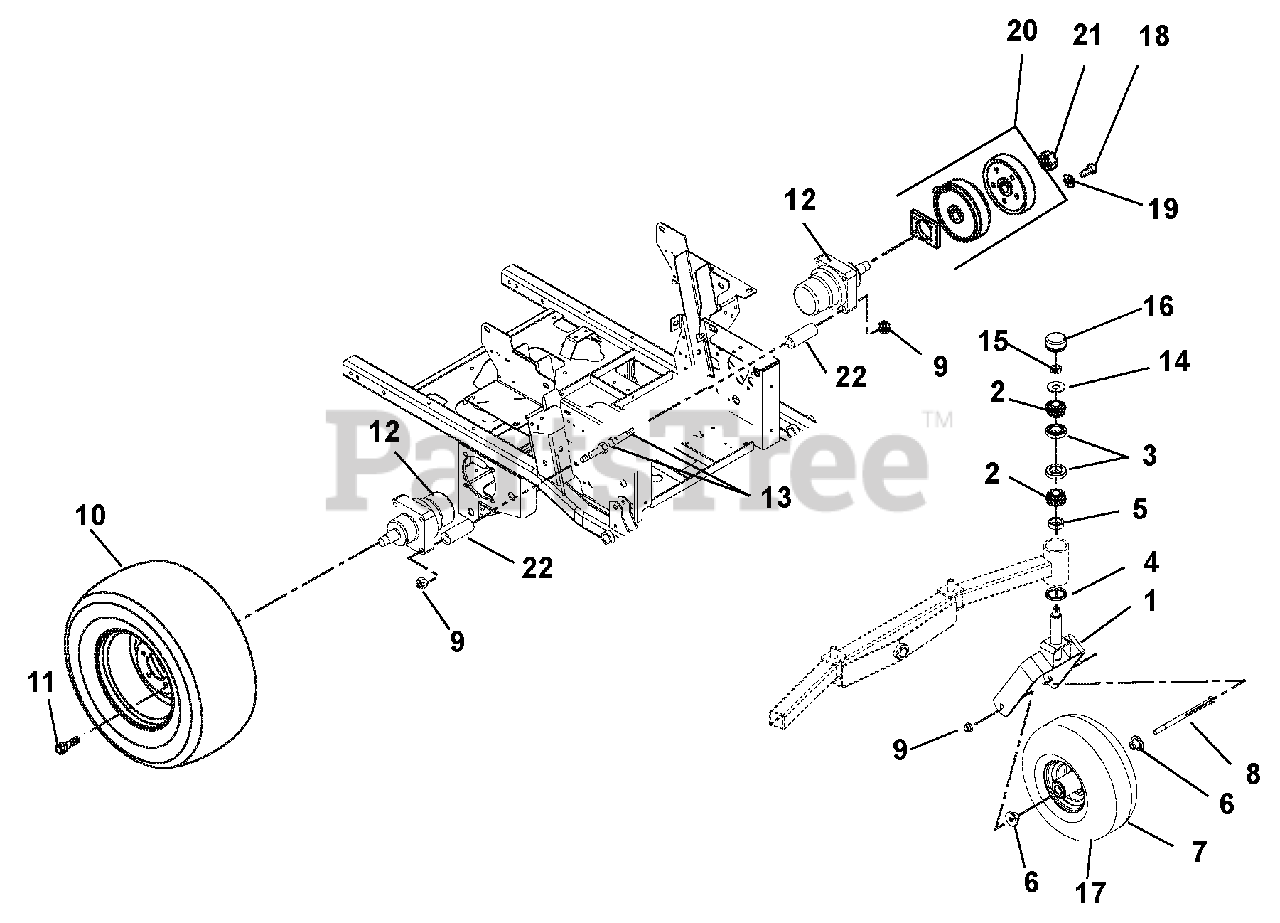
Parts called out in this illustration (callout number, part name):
1	Fork, Front
2	Bearing, Cone
3	Bearing, Cup 2.328 x .465
4	Bearing Seal 1.75 x 2.332 x .312
5	Spacer, 1.258 ID x 1.750 OD x .550
6	Spacer, Wheel
7	Wheel/Tire Assembly, 15 x 6-6, Smooth
8	Bolt, Hex .50-13 x 9.00 Grade 5
9	Nut, Locking Top Flange .50-13
10	Tire/Wheel Assembly, 24 x 11.50-12
11	Bolt, Lug .50-20 x 1.38
12	Wheel Motor, 18E (Counter Clockwise)
13	Bolt, Hex .50-13 x 5.00 Grade 8
14	Washer, Flat Steel, .812 x 2.00 x .148
15	Nut, Jam Center Lock .75-16
16	Cap, Dust
17	Bearing, 25mm I.D. x 52mm OD x 15mm
18	Bolt, Hex .31-18 x 1.50 Grade 8 EP30
19	Washer, Lock .31 x .078
20	Kit, Parking Brake Service
21	Nut, Locking Jam Patch 1.00-20
22	Bushing, .513 x .748 x 2.129
